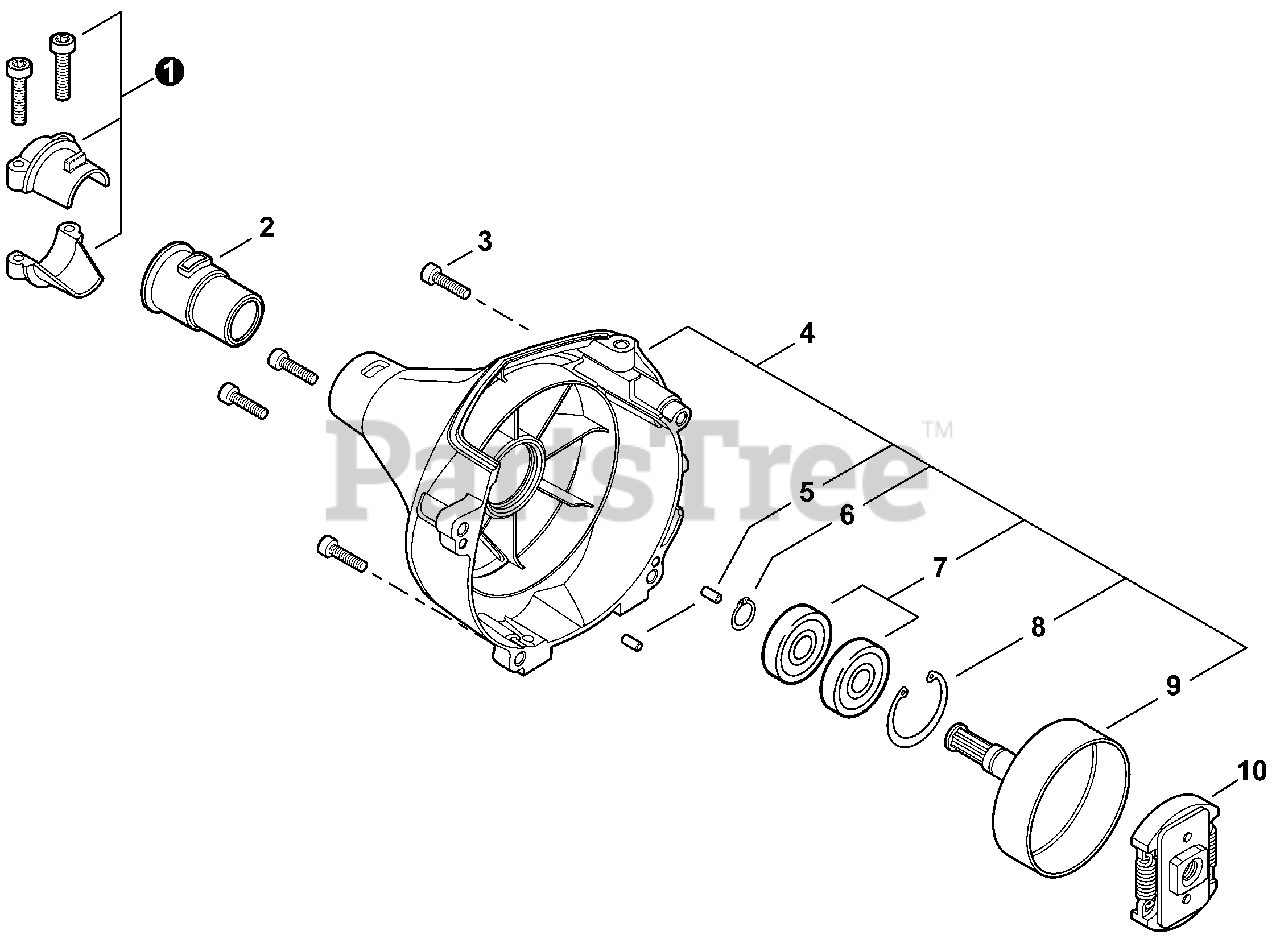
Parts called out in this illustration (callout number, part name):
1	HOLDER KIT
2	CUSHION Ø25
3	BOLT, TORX 4×16
4	COVER ASSY, FAN
5	PIN, LOCATING 4
6	RING, SNAP 12
7	BEARING, BALL 6001
8	RING, SNAP 28
9	DRUM, CLUTCH
10	CLUTCH ASSY
